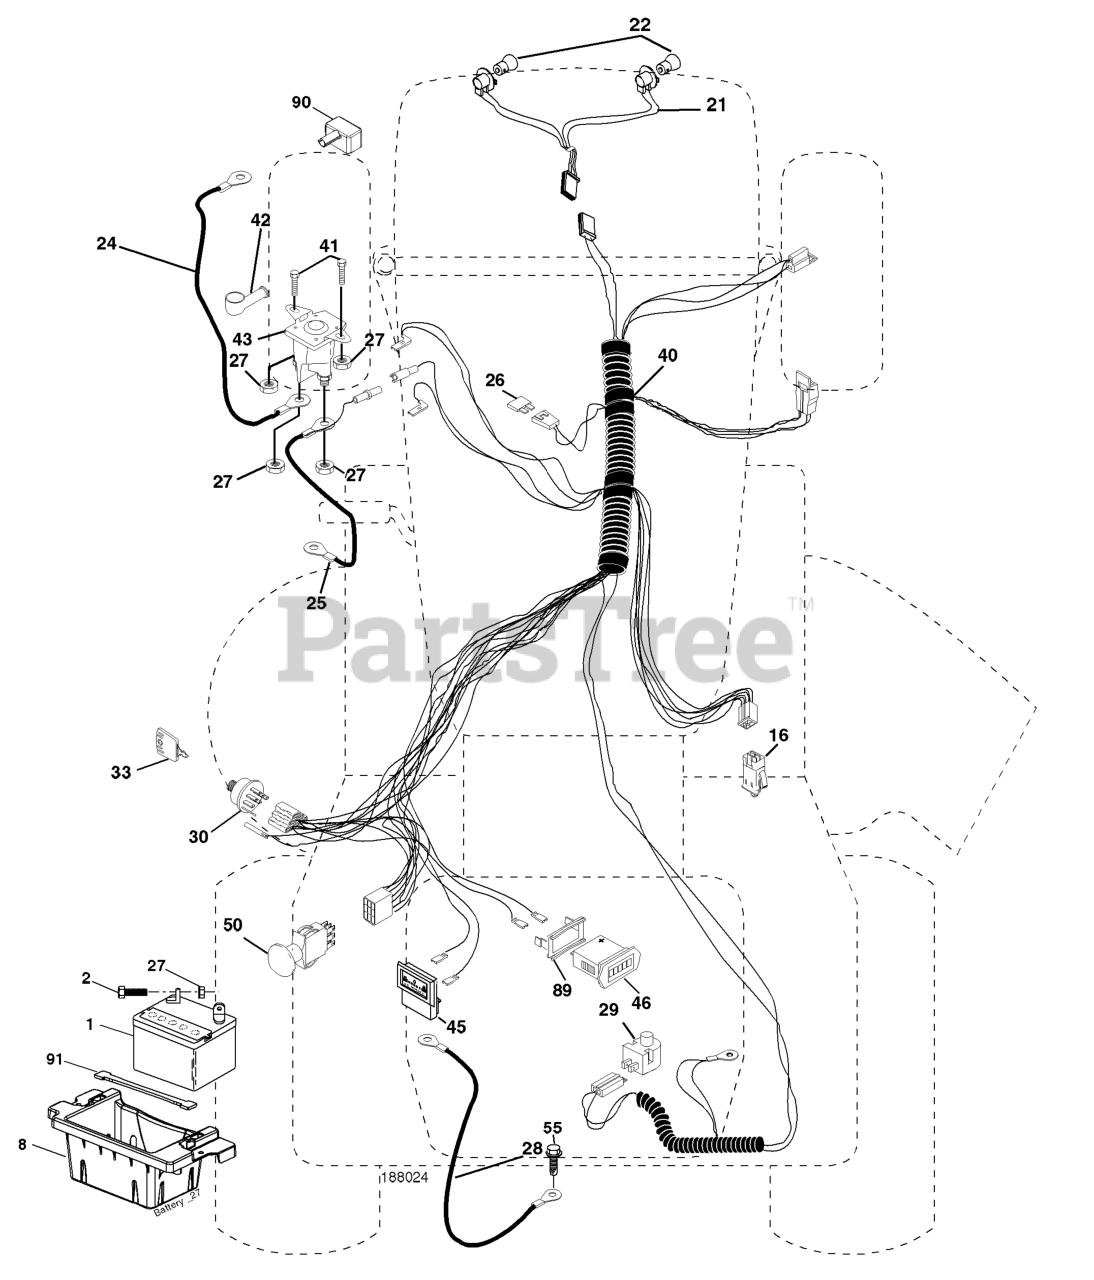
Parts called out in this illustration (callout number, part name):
1	BATTERY 12V .35 AMP
2	BOLT.HEX.1/4.X.3/4.DICHROMATE
8	BOX.BATTERY.MOUNT.FRONT.LT
10	BOLT 1/4-20 X 7.5
11	BATTERY HOLDDOWN FRONT MOUNT
12	NUT, PUSH NYLON 1/4" BATTERY
16	SWITCH INTERLOOK PUSH-IN
21	HARNESS ASSY LIGHT
24	BATTERY CABLE GT
25	CABLE BATTERY 6 GA 22" W/16W
26	FUSE 20AMP
27	NUT
28	CABLE GROUND 6 GA 21" 90T BLK
29	RP.SWITCH.PLUNGER.NC.GRAY
30	IGNITION SWITCH
33	KEY MLD GEN DELTA
40	HARNESS.IGNITION
41	BOLT
42	TERMINAL COVER
43	SOLENOID
46	HOUR METER
50	RP.PTO.SWITCH.8 TERMINAL.BLACK
55	Screw 5/16-18 x 1/2
89	BRACKET SNAP-IN HOURMETER
90	COVER TERMINAL
91	STRAP.BATTERY.MOUNT.FRONT(2 2)
